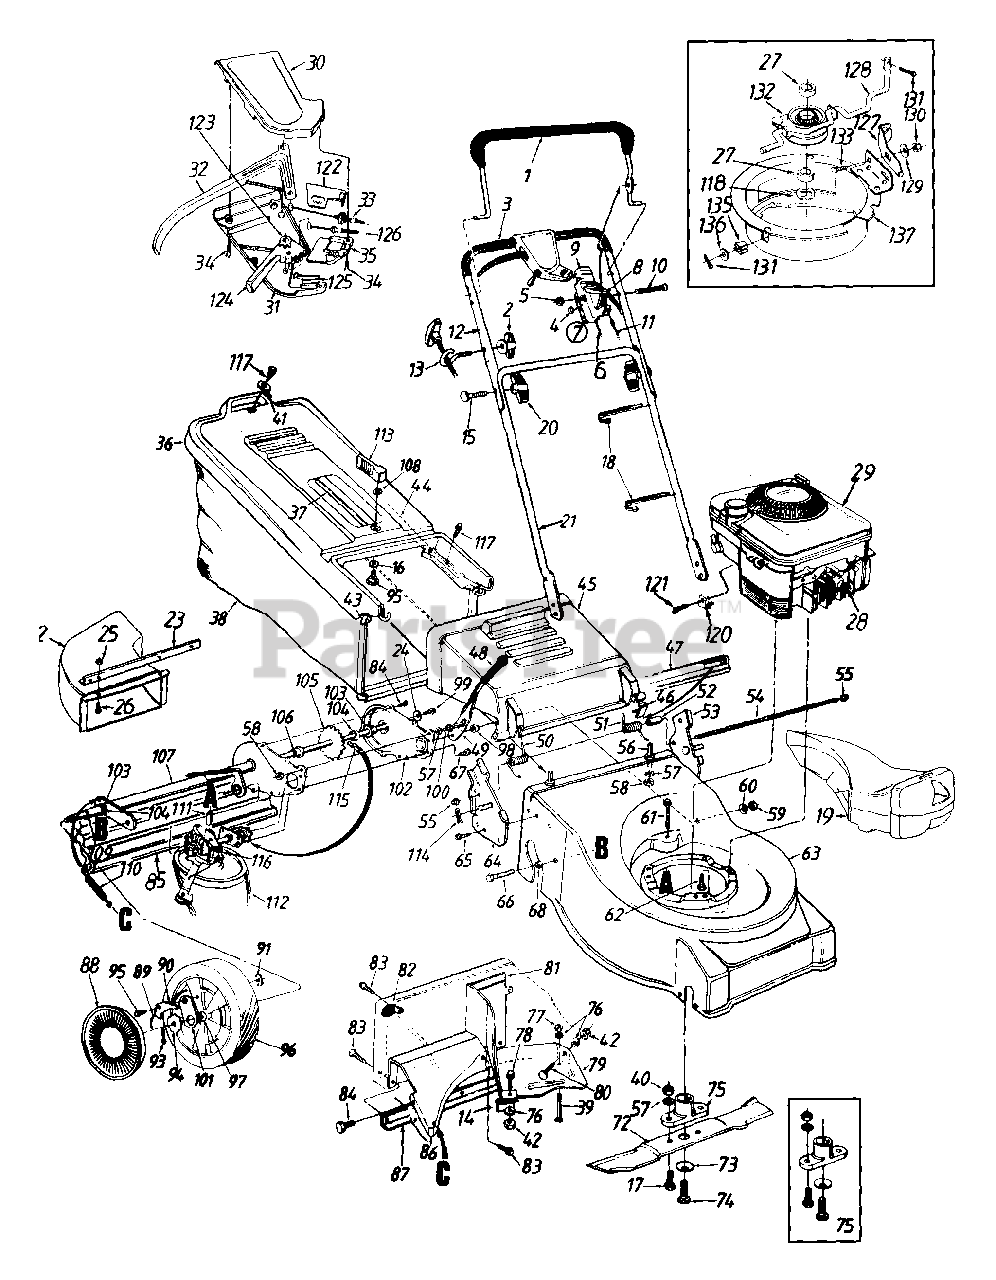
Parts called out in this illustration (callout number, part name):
2	Handle Knob 1/4 - 20 Thd.
3	Foam Grip
4	Spr. Wash..66" I.D.
5	Hex L-Nut 1/4-20 Thd.
6	Throttle Cable - 55"
7	Throttle Box Comp.
8	Throttle Lever
9	Throttle Body
10	Oval C-Sunk Scr.
11	Control Cable - 40.5"
13	Rope Guide
14	Stop Bracket
15	Curved Hd. Bolt 5/16 - 18 x 2"
16	Bowed Washer
17	Hex Bolt 3/8 - 24 x 1" Lg.
18	Cable Tie
19	Mulching Plug
20	Hand Knob
24	Bell-Wash. .265" I.D. x .75"
25	Hex L-Nut 1/4 - 20 Thd.
26	Mach. Scr. 1/4 - 20 x .5" Lg.
27	Spacer .885" I.D.
28	Spark Plug Boot
29	Engine
30	Control Cover Half - Upper
31	Control Cover Half - Lower
32	Control Lever
33	Drive Cable - 51" Lg.
34	Flat C-Sunk Hd. Tap Scr. #10 x .75" Lg.
35	S.P. Control Cover
36	Hardtop Bag Cover
37	Hardtop Handle
38	Grass Bag
39	Truss Mach. Scr. 1/4 - 20 x 1.0" Lg.
40	Hex Nut 3/8 - 24 Thd.
41	Fl-Wash. .281" I.D. x .62"
42	Hex Nut 1/4 - 20 Thd.
44	Rear Catcher Frame
45	Chute Deflector
46	Deflector Plug
47	Seal - Extrusion
49	Spring Lever
50	Torsion Spring - R.H.
51	Torsion Spring - L.H.
52	Spacer .255" I.D.
55	Cap Speed Nut
56	Shld. Pin 3/8-24 x 1.43" Lg.
57	L-Wash. 3/8" I.D.
58	Hex Jam Nut 3/8 - 24 Thd.
59	Hex L-Nut 3/8 - 24 Thd.
60	Bell-Wash. .38" I.D. x .88"
61	Hex Tap Scr. 1/4 - 20 x 1.5" Lg.
62	Hex Tap Hd. Scr. 3/8 - 16 x 1" Lg.
63	21" Deck Ass'y.
66	Hex Tap Scr. 3/8-16 x .75" Lg.
67	Hex Tap Scr. 1/4-20 x .5" Lg.
68	Spacer .383" I.D.
72	21" Blade
73	Bell-Wash. .46" I.D.
74	Hex Bolt 7/16 - 20 x 1.5" Lg.
75	Blade Adapter Kit
76	L-Wash. 1/4" I.D.
77	Hex Jam Nut 1/4 - 20 Thd.
78	Pan Hd. Mach. Scr. 1/4 - 20 x 1" Lg.
83	Torx Mach. AB-Tap Scr. 1/4 x 62" Lg.
84	Hex Wash. Hd. Tap Scr. 1/4 x .38" Lg.
85	Rear Flap
89	Plastic Spring
90	Pawl .345" 1.D.- R.H.
91	Weld Top L-Nut 1/4 - 20 Thd.
93	Cotter Pin 1/8" Dia.
94	Ratchet Wheel 1.62" O.D.
95	Shld. Bolt .342" Dia. x .268"
96	Rear Wheel Ass'y. Comp.
97	Bearing 1/2" I.D.
98	Shld. Spacer .50" Dia.
99	Hex Bolt 1/4 - 20 x .62" Lg. (Gr. 5)
100	Shld. Pin 3/8 - 24 x 1.43" Lg.
101	Pawl Plate
104	Fl-Wash. .531" I.D. x .93"
105	Rear Axle Ass'y.
106	Hex Flange Bearing
109	Spacer .513" I.D.
110	Extension Spring 3.8" Lg.
111	Spacer .325" I.D.
112	V-Belt
113	Grass Catcher Locking Knob
114	Internal Cotter Pin 5/16" Dia.
115	#48 Chain .50" Pitch x 30 Links
116	Transmission Comp.
117	Hex AB-Tap Scr. 1/4 x .62" Lg.
118	Wave Wash..88" I.D. x 1.38" O.D.
120	Cable Clamp
121	Hex Self-Tap Scr. #10 - 32 x .62" Lg.
122	6-Speed Rack Cable Brkt.
123	3 Tooth Rack Gear Insert
124	6-Speed Shift Lever
125	Shift Lever Spring
126	Spd. Control Cable
129	Bell-Wash..265" I.D. x .75"
130	Hex Cent. L-Nut 1/4 - 20 Thd.
131	Cot-Pin 3/32" Dia. x .75" Lg.
132	Pulley Ass'y.
133	Carr. Bolt 1/4 - 20 x .5" Lg.
135	Flanged Bushing
136	Fl-Wash. .328" I.D. x 68" O.D.
